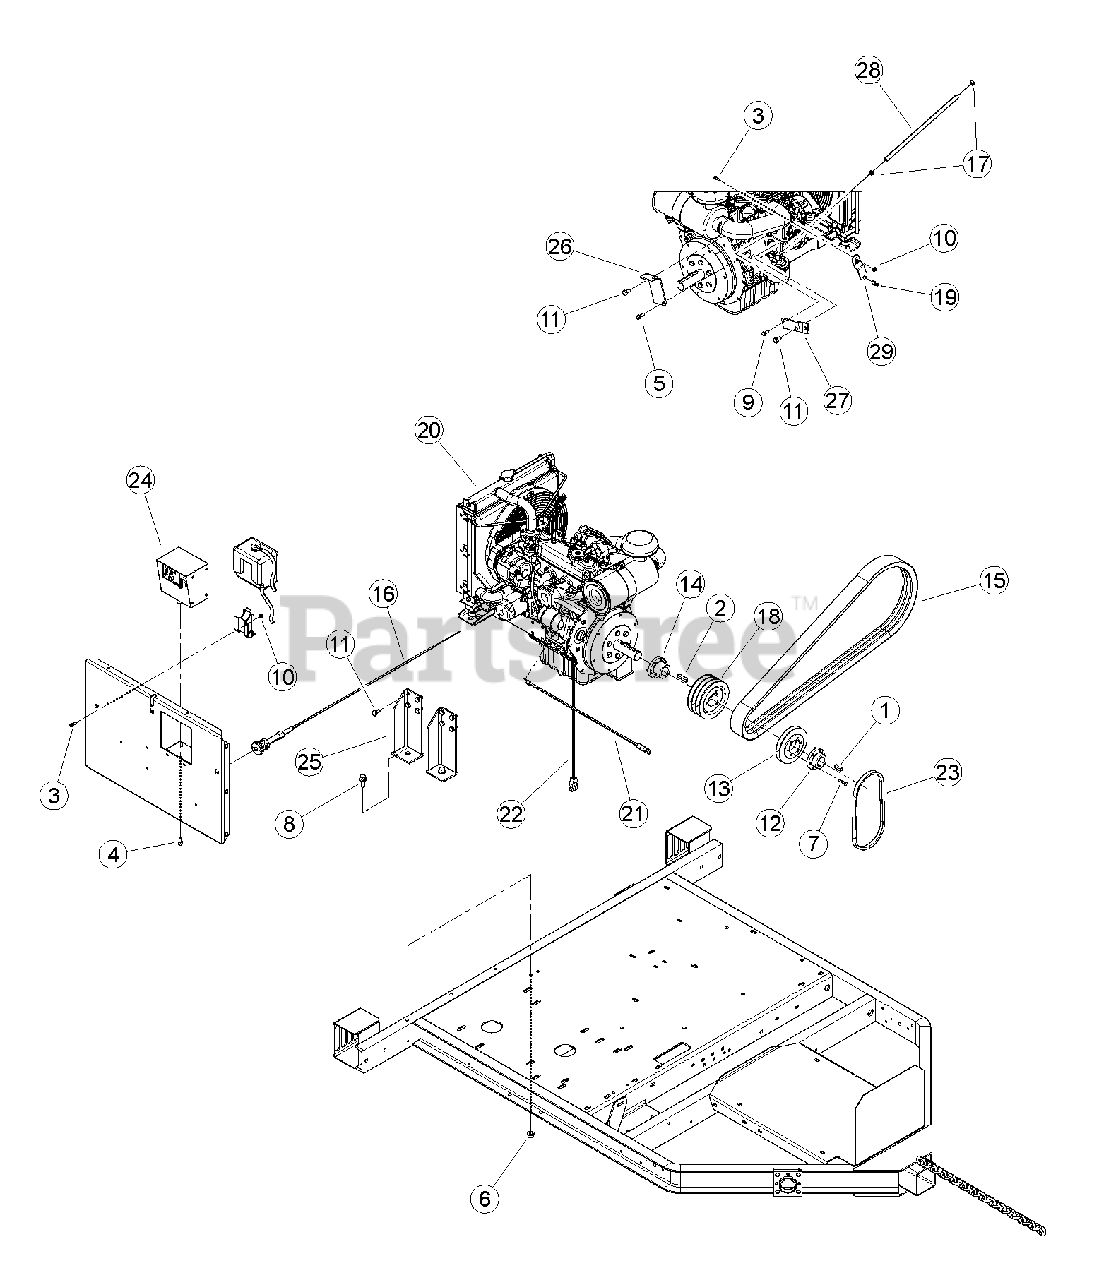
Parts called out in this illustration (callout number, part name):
1	KEY, 3/8 SQ X 1-1/4
2	KEY, 3/8 SQ 1-3/4
3	BOLT, 1/4-20X3/4,HWH,GR5,CZP
4	BOLT, 5/16 X 3/4 FLANGE NC
5	BOLT, 5/16 X 1 FLANGE NC
6	NUT, 1/2-13 NYLOCK FLANGE
7	BOLT, 1/4-20 X 1-1/4 GR5 HHCS MAGNI 565 SILVER
8	BOLT, 1/2 -13 X 1-1/4 FLANGE NC
9	BOLT, M 8-1.25 X 20 GR8.8 HHD ZP
10	NUT, 1/4-20 NYLOCK-FLANGE
11	BOLT, M10 X 1.25 X 20 GR10.9 HEX HEAD ZP
12	BUSHING, SDS 1-7/16"
13	SHEAVE, 1B5.2 SDS
14	BUSHING, SD 1-7/16"
15	BELT, 3B83 BANDED
16	CABLE, DIESEL THROTTLE
17	CLAMP, 9/16 SPRING
18	SHEAVE, 3BQ5.6, SD
19	CABLE STOP, BOWDEN PIN # 6170
20	ASSEMBLY, 28 HP KUBOTA DIESEL ENGINE
21	CABLE, 72" POSITIVE BATTERY
22	CABLE, 72" NEGATIVE BATTERY
23	BELT, BX30
24	CONTROLLER, DSE - KUBOTA
25	WELDMENT, ENGINE MOUNT
26	ANGLE, SPRING ANCHOR
27	STRIP, CABLE ANCHOR
28	HOSE, 15 INCH FUEL LINE
29	STRIP, THROTTLE CONTROL
